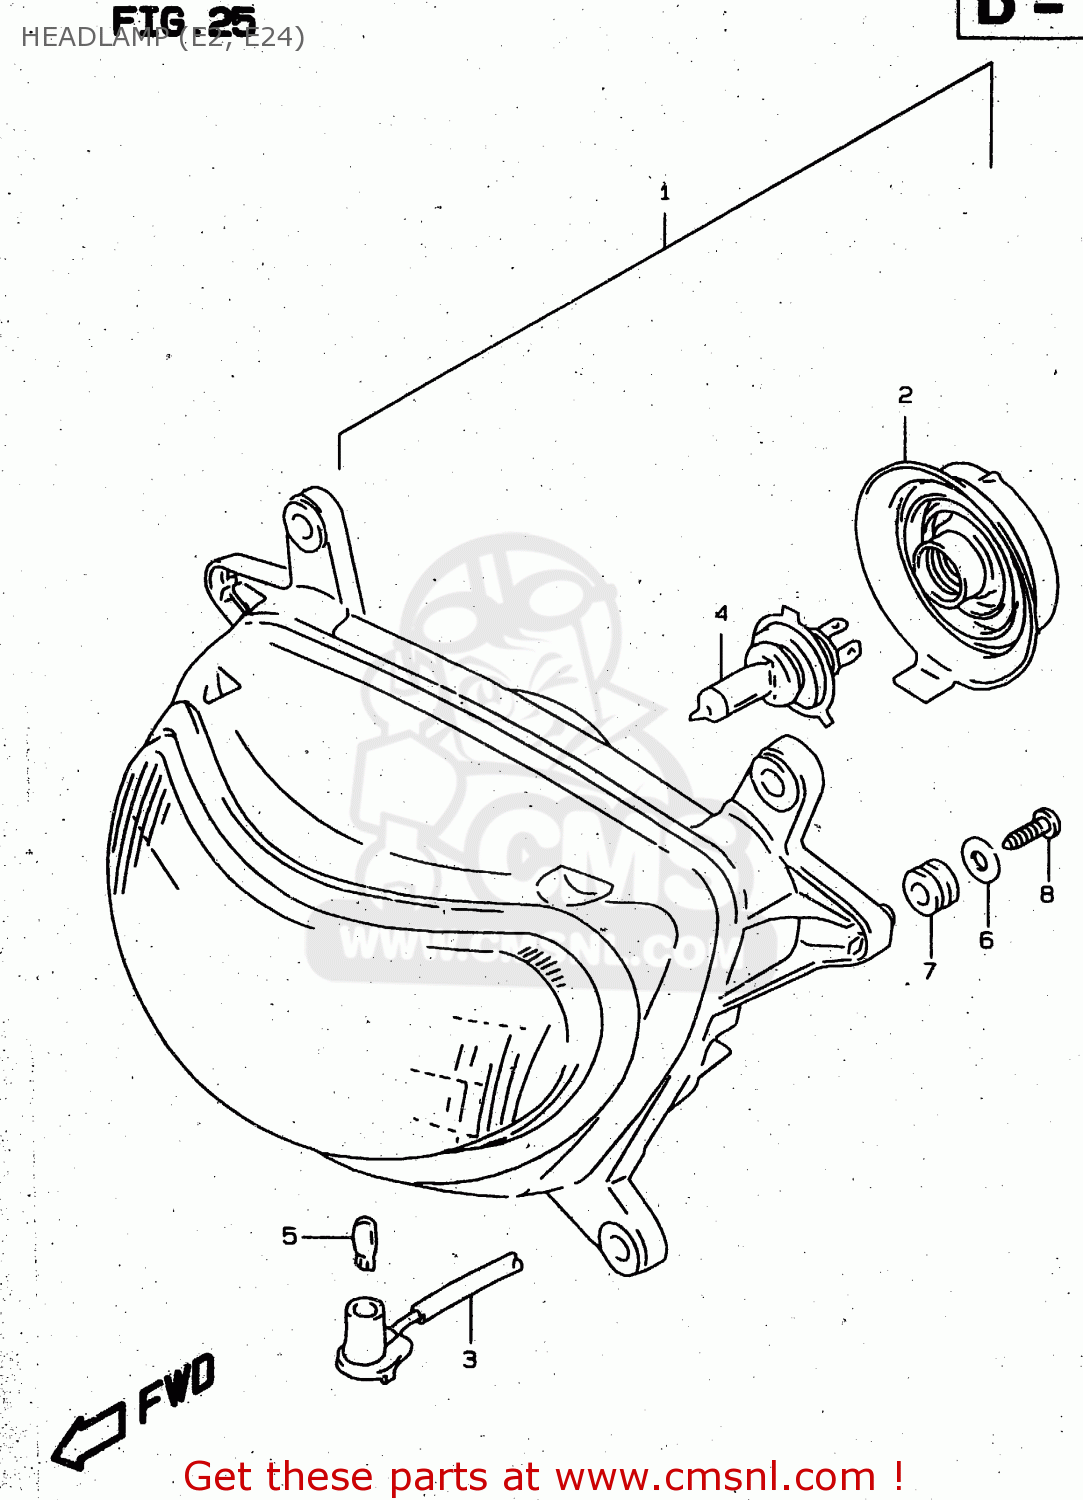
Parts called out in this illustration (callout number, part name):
1	HEADLAMP ASSY
2	COVER
3	CORD ASSY
4	BULB(12V60/55W,H4)
5	BULB(12V5W)
6	WASHER(5.5X18X1)
7	CUSHION
8	SCREW
